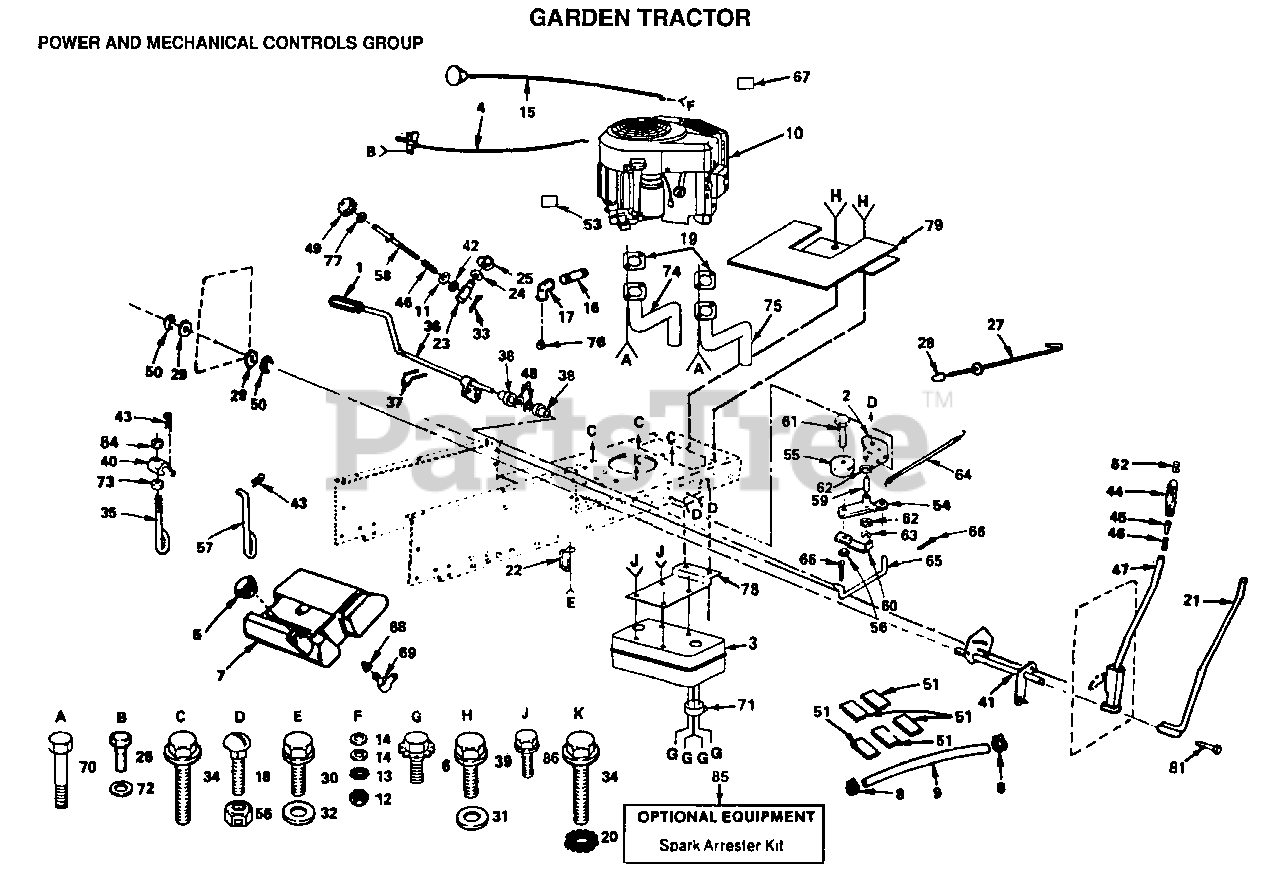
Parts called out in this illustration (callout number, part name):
2	BRKT ASM
6	SCREW LT
8	HOSE CLAMP
9	FUEL LINE T
10	PIPE, EXHAUST
11	WASHER
13	LOCKWASHER
14	WASHER
16	PIPE NIPPLE LT
17	ELBOW
18	BOLT
20	LOCKWASHER
21	LEVER ROD LT
22	RETAINER BELT
23	TRUNION LT
24	WASHER
25	KLIP RING
26	SCREW
27	ROD BRAKE PARK
28	PLUNGER CAP T
29	WASHER
30	SCREW
31	WASHER
32	WASHER
34	SCREW LT
35	PIVOT PIN T
38	NYLON BEARING
39	SCREW
41	SHAFT LIFT LT
42	NUT T
44	GRIP
46	SPRING T
48	WASHER LT
49	HDLE ADJ LIFT
50	E-RING
51	PAD-SPACER T
53	DECAL, MAINTENANCE
54	ARM IDLER
57	LIFT LINK LT
58	ROD LIFT LT
59	"LY, BEARING"
60	RETAIN BELT
62	WASHER LT
63	KLIP RING
64	"SPRING, RETURN LT"
65	"LINK, CLUTCH T"
66	COTTER PIN
67	DECAL, ENGINE INSTRUCTION
68	BUSHING OUTLET T
69	FUEL TANK STEM GT
71	DEFLECTOR.222573
73	NUT
74	TUBE ASSY EXH LH
75	TUBE ASSY EXH RH
76	PLUG OIL DRAIN
77	NUT
78	BRACKET MUFFLER
81	"BOLT,HEX"
86	SCREW ST
